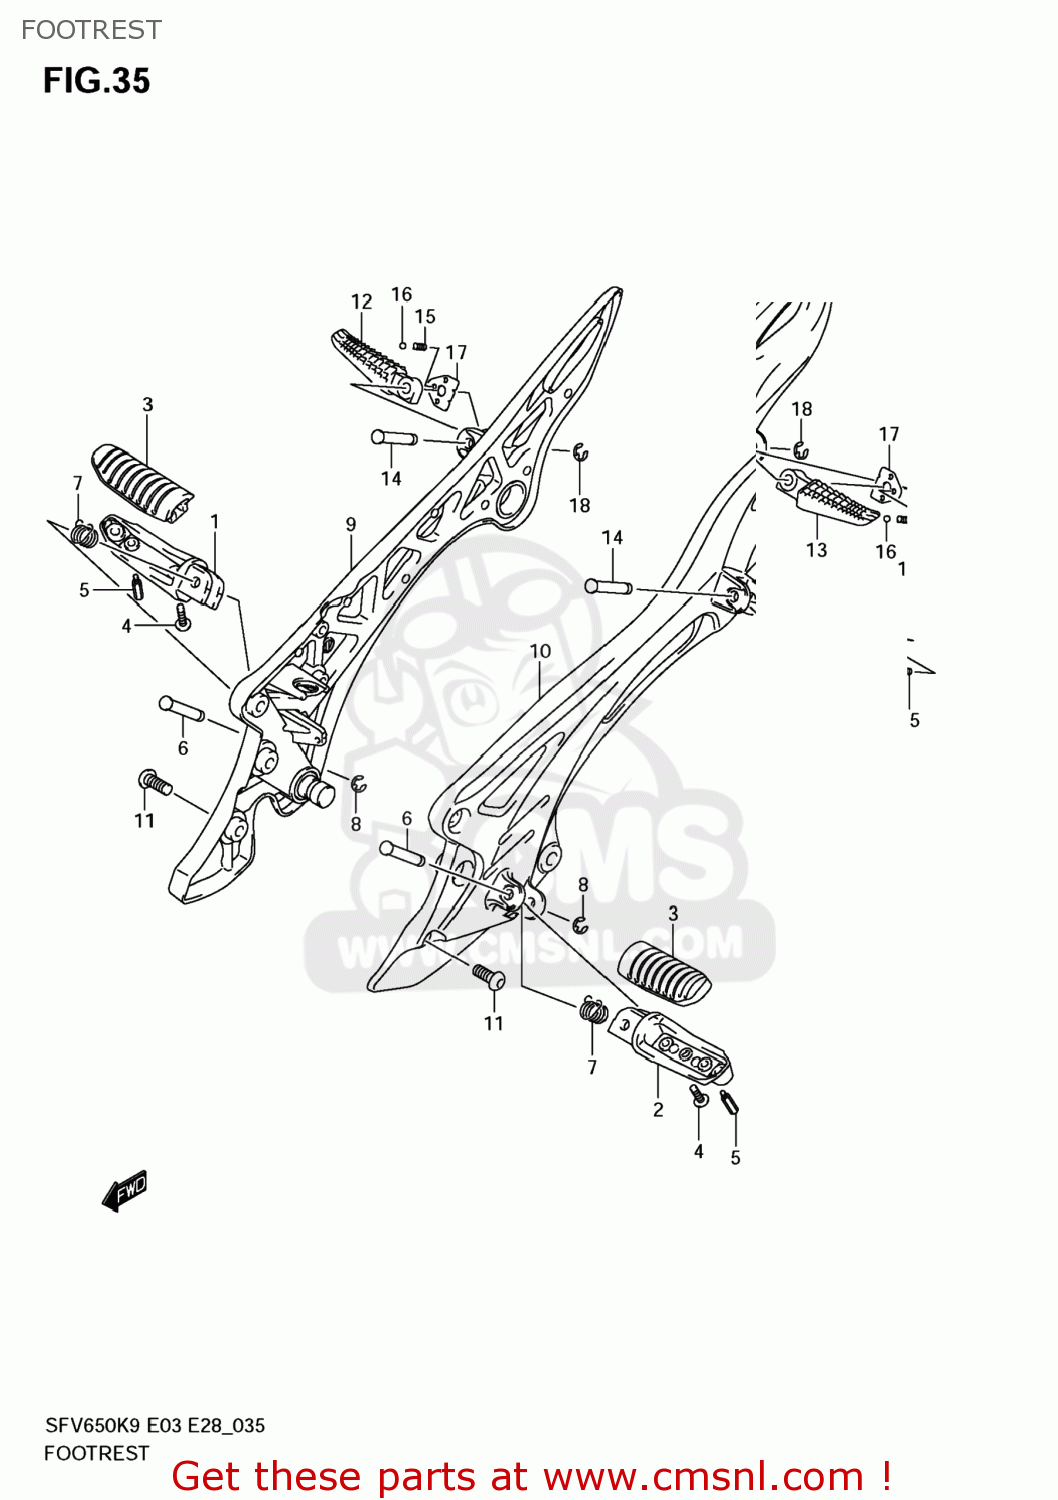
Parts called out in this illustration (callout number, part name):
1	BAR,FR FOOTREST,R
2	BAR,FR FOOTREST,L
3	RUBBER,FOOTREST BAR
4	SCREW
5	SENSOR,FOOTREST
6	PIN
7	SPRING
8	E RING
9	BRACKET COMP,F
10	BRACKET,FOOTREST,L
11	BOLT(8X20)
12	BAR,PILLION FOOTREST,R
13	BAR,PILLION FOOTREST,L
14	PIN
15	SPRING
16	BALL
17	PLATE,PILLION FOOTREST
18	E RING
